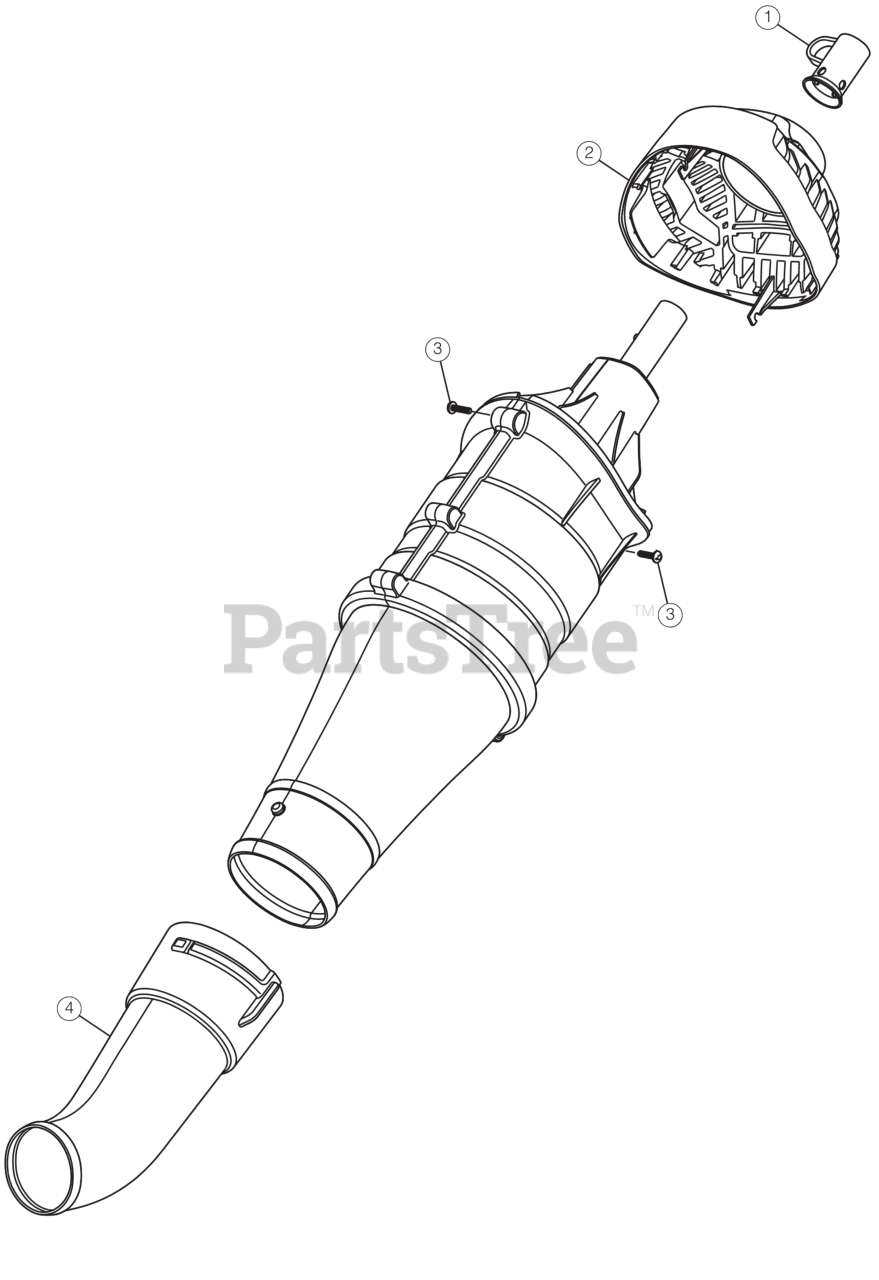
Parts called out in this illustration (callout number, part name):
1	HANGER
2	INTAKE REAR BLOWER
3	SCREW 8-16 x 3/4
4	NOZZLE BLOWER ATACH
